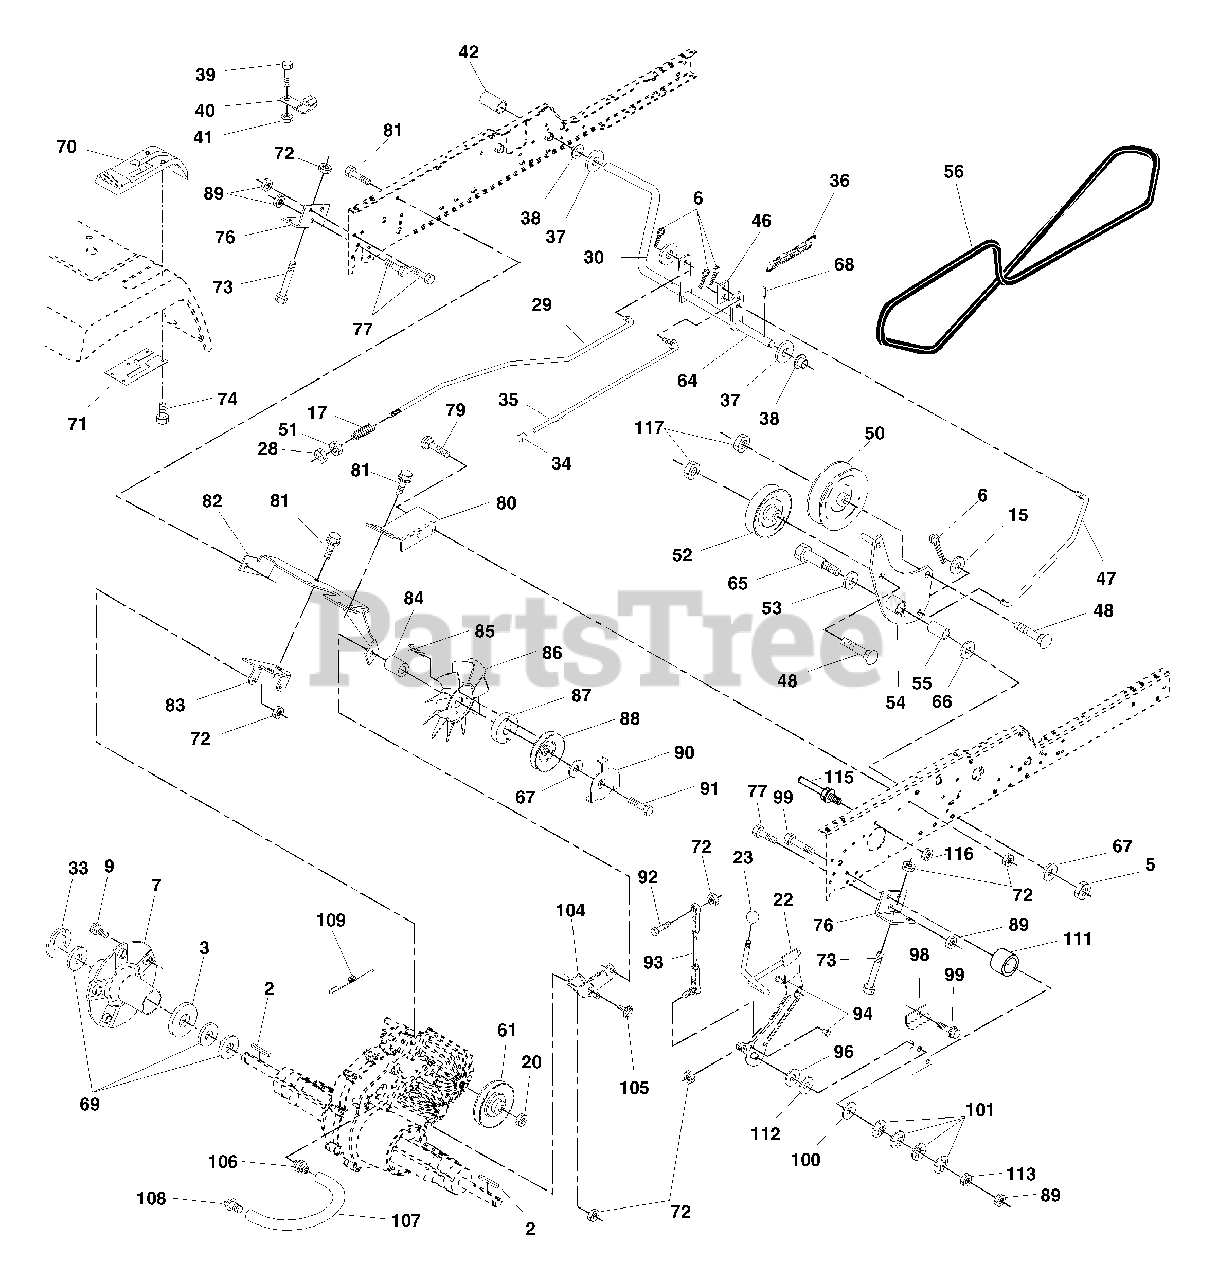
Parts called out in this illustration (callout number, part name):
2	Key 1/4 x 2.5
3	Washer Thrust Axle Harden
5	Nut Crownlock 3/8-16
6	Pin Cotter 1/8 x 3/4
7	Wheel Hub Asm.
9	Bolt Hub
15	Washer 13/32 x 13/16 x 16 Ga
17	Spring Rod Brake
20	Nut Hex Jam Toplock 1/2-20 UNF
22	Shift Arm Asm
23	Knob
28	Nut
29	Brake Rod
30	Washer 13/32 x 1 x 16 Ga.
33	Ring E
34	Cap Plunger
35	Rod Parking Brake
36	Spring Drive Ground
37	Washer 25/32 x 1-1/4 x 16 Gauge
38	Nyliner, Bushing
39	Screw Fin #10-24 x 1
40	Actuator Interlock Switch
41	Nut Lock #10-24
42	Cover Pedal
46	Retainer Spring
47	Clutch Rod
48	Bolt Carriage 3/8-16 x 1-1/2 Gr 5
50	Pulley Idler Flat
51	Nut Crownlock 3/8-16 UNC
52	Pulley Idler Grooved
53	Washer Hartdened
54	Arm Asm Idler Clutch 98
55	Bearing, Idler
56	V-Belt
61	Pullery Transaxle
64	Shaft Asm Brake Parking Clutch
65	Bolt Shoulder
66	Washer Hardened
67	Washer 13/32 x 13/16 x 12 Ga
68	Pin Roll
69	Washer
70	Console Hydro Fender
71	Plate Console Shift
72	Nut Crownlock 5/16-18
73	Bolt Hex FLGHD 5/16-18 x 3 Gr. 5
74	Screw Hex Wsh. Hi-Lo 1/4-1/2
76	Bracket Transaxle
77	Bolt Fin Hex 7/16-14 x 1
79	Bolt Carriage 5/16-18 x 5/8
80	Bracket Torque RH
81	Screw 3/8-16 x 3/4
82	Bracket Mount Torque/Fan
83	Strap Torque Mid
84	Spacer
85	Screw #10-24 x 1-1/4
86	Fan 7" Hydro
87	Adapter Fan
88	Pulley Idler
89	Nut Crownlock 7/16-14 UNC
90	Keeper Belt
91	Screw Thdrol 3/8-16 x 2-3/4
92	Bolt Fin Hex 5/16-18 x 1.25
93	Link Shift Asm
94	Fastner Christmas Tree
96	Washer Nickel Plated
98	Bracket Shift
99	Screw 3/8-16 x 1-1/2
100	Washer Compression
101	Washer Bellville
104	Bracket Idler
105	Screw Tap 1/4-20 x 1/2
106	O-Ring Asm. Hydro Ger 70110
107	Line Fuel Hydro 15" Vgt Serv
108	Cap Asm Vent Hydro Gear 70109
109	Spring Return Brake
111	Spacer Shift Leer Vgth
112	Washer Nylon High Temp
113	Nut, Hex Asf 7/16-14 UNC
115	Keeper Belt T/A Gnd Dr. LR
116	Nut Lock Hex Flange 5/16-18
117	Nut Lock Flange 3/8-16 UNC
118	Nut Lock Hx W/Ins 5/16-18 UNC
